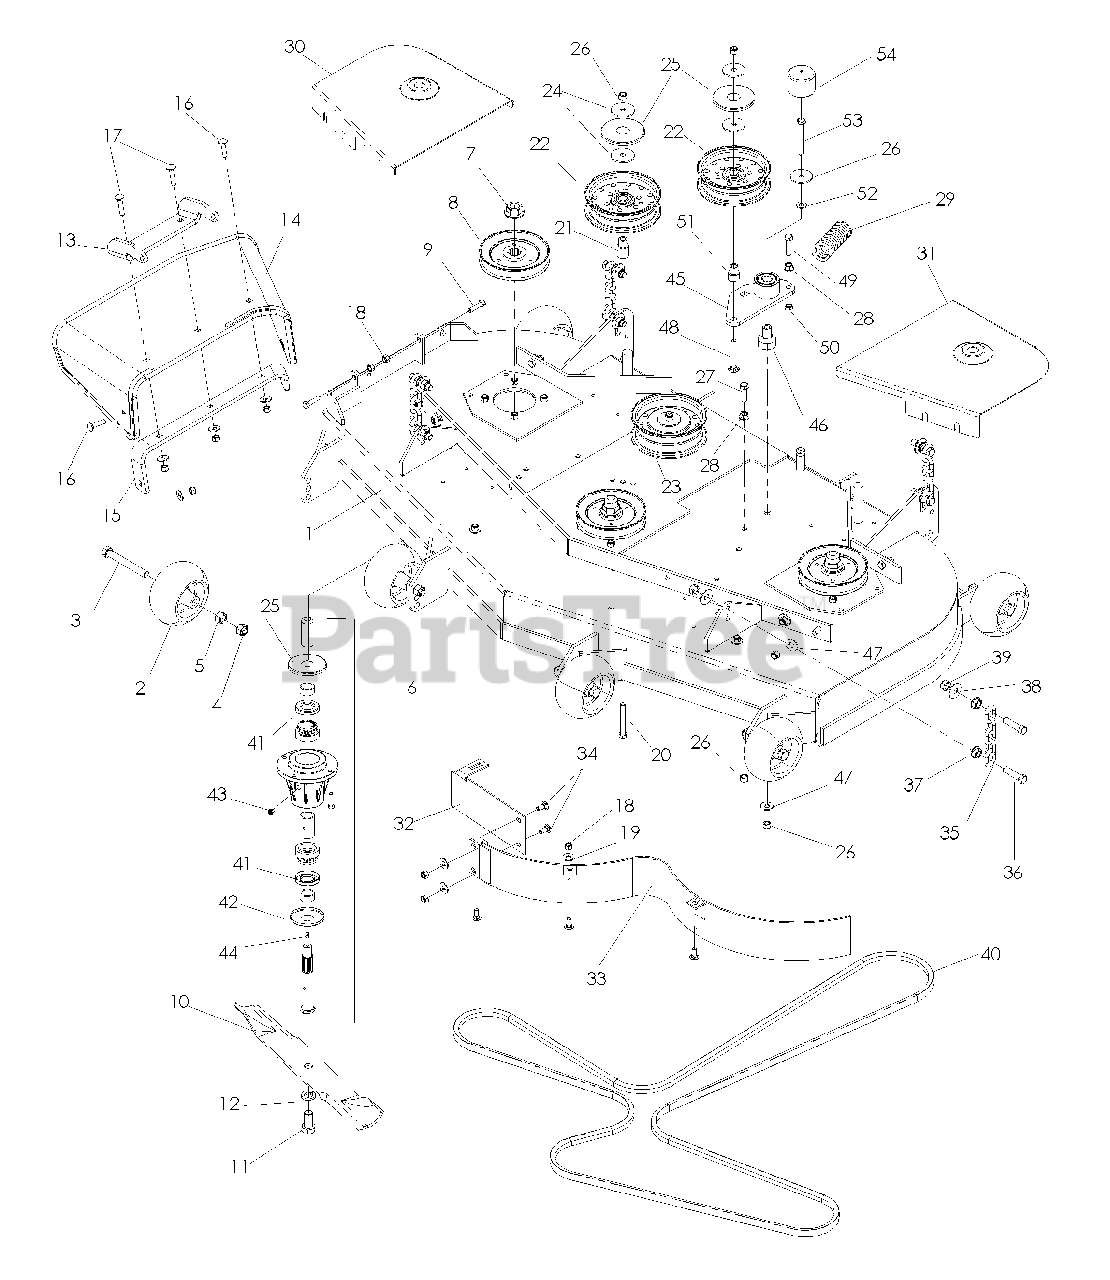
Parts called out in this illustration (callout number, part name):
1	DECK W/DECALS
2	WHEEL, GAUGE
3	HCS 1/2-13 x 4
4	NUT 1/2-13 HEX NYLOC
5	NUT 1/2-13 HEX
6	HOUSING ASSM, 52/61
7	NUT, FLANGE 3/4-16
8	PULLEY, 52
9	HCS 5/16-18 x 1 1/4
10	BLADE, 18"
11	HCS 5/8-18 x 1 1/4
12	WASHER 5/8 SLW
13	PIVOT BRACKET, CHUTE
14	RUBBER CHUTE, 52/61
15	BRACKET, REINFORCE
16	RHSNB 5/16-18 x 1 1/4
17	RHSNB 5/16-18 x 1 1/2
18	NUT 5/16-18 HEX NYLOC
19	WASHER 5/16 STD FLT
20	HCS 3/8-16 x 2 3/4
21	BUSHING, IDLER
22	PULLEY, IDLER
23	PULLEY, IDLER
24	WASHER 3/8 SPECIAL
25	TOP DUST CAP
26	NUT 3/8-16 HEX NYLOC
27	HCS 3/8-16 x 1 1/4
28	NUT 3/8-16 HEX WHIZLK
30	SHIELD RT 52
31	SHIELD LT 52
32	BAFFLE MAIN
33	BAFFLE CENTER
34	RHSNB 5/16-18 x 3/4
35	LIFT CHAIN
36	HCS 7/16-14 x 1 3/4
37	NUT 7/16-14 HEX WHIZLK
38	WASHER 7/16 FLAT
39	NUT 7/16-14 HEX NYLOC
40	BELT, DECK 52"
41	SHAFT SEAL
42	BOTTOM DUST CAP
43	GREASE POPPET
45	ARM, IDLER, W/BEARINGS
46	PIVOT, BEARING
47	WASHER 3/8 STD FLT
48	RHSNB 3/8-16 x 2 3/4
49	HCS 3/8-16 x 1 1/2 GR 8
50	NUT 3/8-16 HEX JAM
51	BUSHING, IDLER
52	WASHER 3/8 SAE FLT
53	HCS 3/8-16 x 3
54	CAP, VINYL
